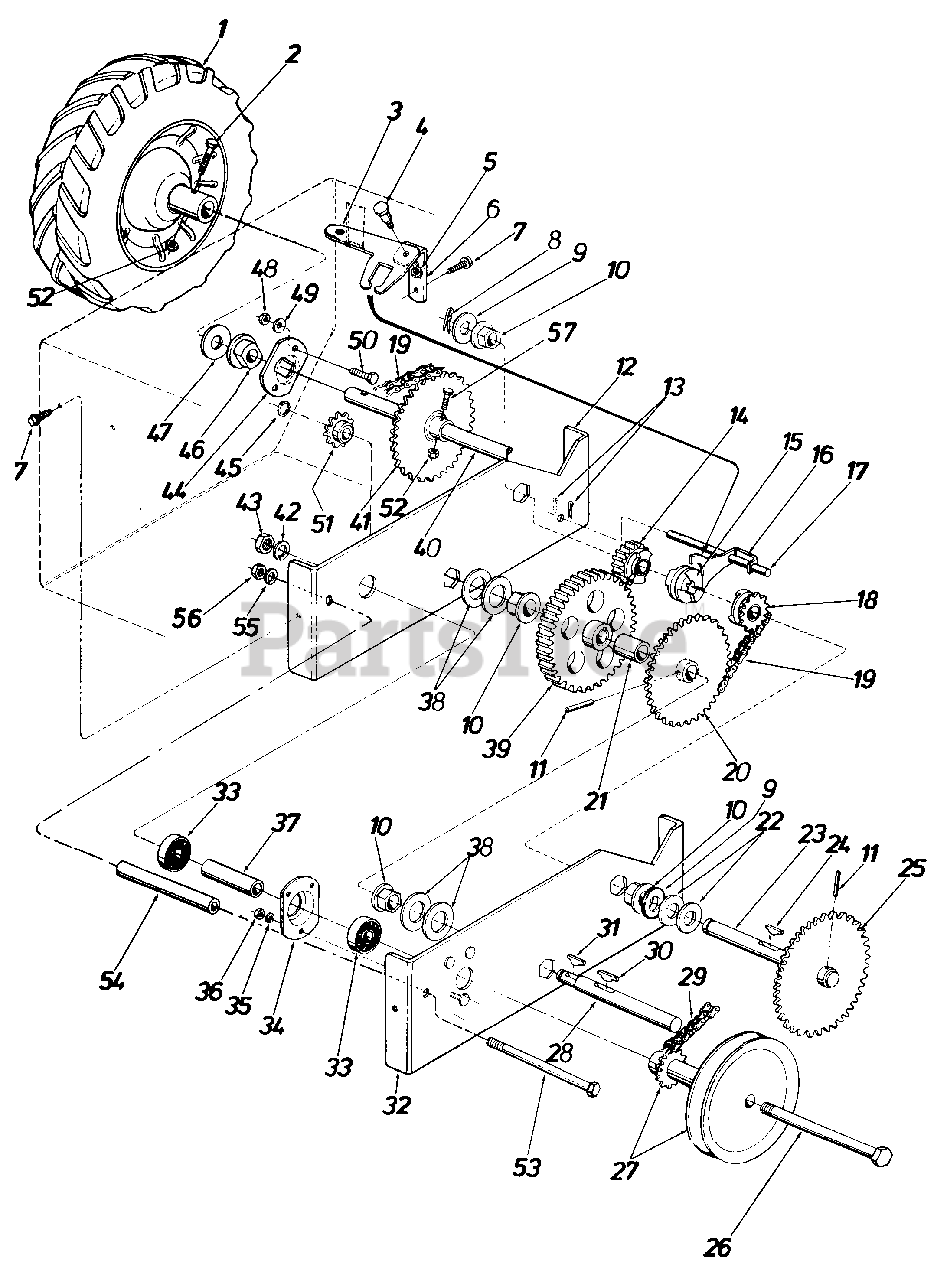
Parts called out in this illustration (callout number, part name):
1	Wheel Ass'y. Comp. 12.5 x 3.5 R.H.
2	Hex Bolt 5/16-24 x 1.50" Lg. H .T.
3	Shifting Bracket
4	Shld. Scr. .438" Dia. x .180 Lg.
5	Hex Ins. L-Nut 5/16-18 Thd.
6	Shifting Bracket Support
7	Hex Wash. Hd. Self-Tap Scr. 5/16-24 x .50
8	Cotter Pin 3/32 Dia. x 1.00" Lg.
9	Fl-Wash. .64 I.D. x 1.25 O.D. x .060
10	Hex Flange Brg. .63 I.D.
11	H-Spring Pin Spiral 1/4" Dia. x 1.50 Lg.
12	Drive Housing Bracket R.H.
13	Internal Cotter Pin 3/8 Dia.
14	Spur Gear 21 Teeth
15	Clutch Collar
16	Shifting Yoke
18	Sprocket 10 Teeth
19	#41 Chain 1/2" Pitch x 33 Links
20	28 Teeth Sprocket Hub Ass'y.
21	Spacer .62 I.D. x .88 O.D. x 1.030
22	Fl-Wash. .64 I.D. x 1.25 O.D. x .100
23	Shifting Shaft
24	Hi-Pro Key 3/16 x 3/4" Dia. x 1 .062
25	32 Teeth Sprocket Hub Ass'y.
26	Hex Scr. 1/2-20 x 5.50" Lg.
27	5.25" O.D. Pulley with 9 Teeth Sprocket
28	Shaft
29	#41 Chain 1/2 Pitch x 47 Links
30	Hi-Pro Key 3/16 x 3/4" Dia.
31	Hi-Pro Key 3/32 x 5/8" Dia.
32	Drive Housing Bracket Ass'y. L.H.
33	Ball Bearing .500 I.D. x 1.38 O.D. x .438
34	Bearing Housing
35	L-Wash. 1/4 Scr.
36	Hex Nut 1/4-20 Thd.
37	Spacer .52 I.D. x .62 O.D. x 2.69
38	Fl-Wash. 1.06 I.D. x 1.75 O.D. x .100
39	Spur Gear 62 Teeth
40	Wheel Axle
41	32 Teeth Sprocket Hub Ass'y.
42	L-Wash. 1/2" I.D.
43	Hex Ins. Jam L-Nut l/z-20 Thd.
44	Bearing Plate
45	External C-Ring
46	Flange Bearing w/Flats .753 I.D.
47	Fl-Wash. .81 I.D. x 1.25 O.D. x .060
48	Hex Nut 5/16-18 Thd.
49	Bell-Wash. 5/16" I.D.
50	Carriage Bolt 5/16-18 x .75n Lg.
51	8 Teeth Sprocket #41 Chai n
52	Hex Jam L-Nut 5/16-24 Thd.
53	Hex Bolt 5/16-18 x 4.0" Lg.
54	Spacer 3.25" Lg.
55	L-Wash. 5/16" I.D.
56	Hex Nut 5/16-18 Thd.
57	Hex Bolt 5/16-24 x 1.5" Lg.
